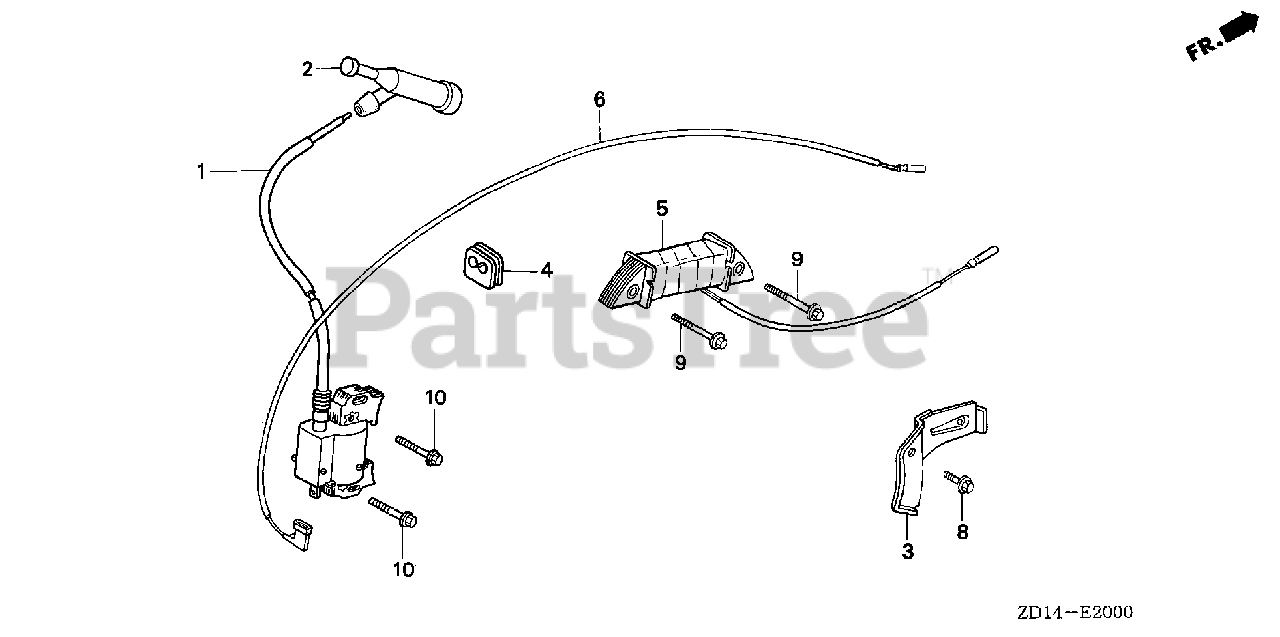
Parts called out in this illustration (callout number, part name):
1	COIL ASSY., IGNITION
2	CAP ASSY., NOISE SUPPRESSOR (NICHIWA Y-EZ RTFM256)
3	CLAMP, WIRE
4	GROMMET, WIRE
5	COIL ASSY., CHARGE (1A)
6	WIRE, STOP SWITCH (470MM)
8	BOLT, FLANGE (6X12) (CT200)
9	BOLT, FLANGE (6X35) (CT200)
10	BOLT, FLANGE (6X28) (CT200)
